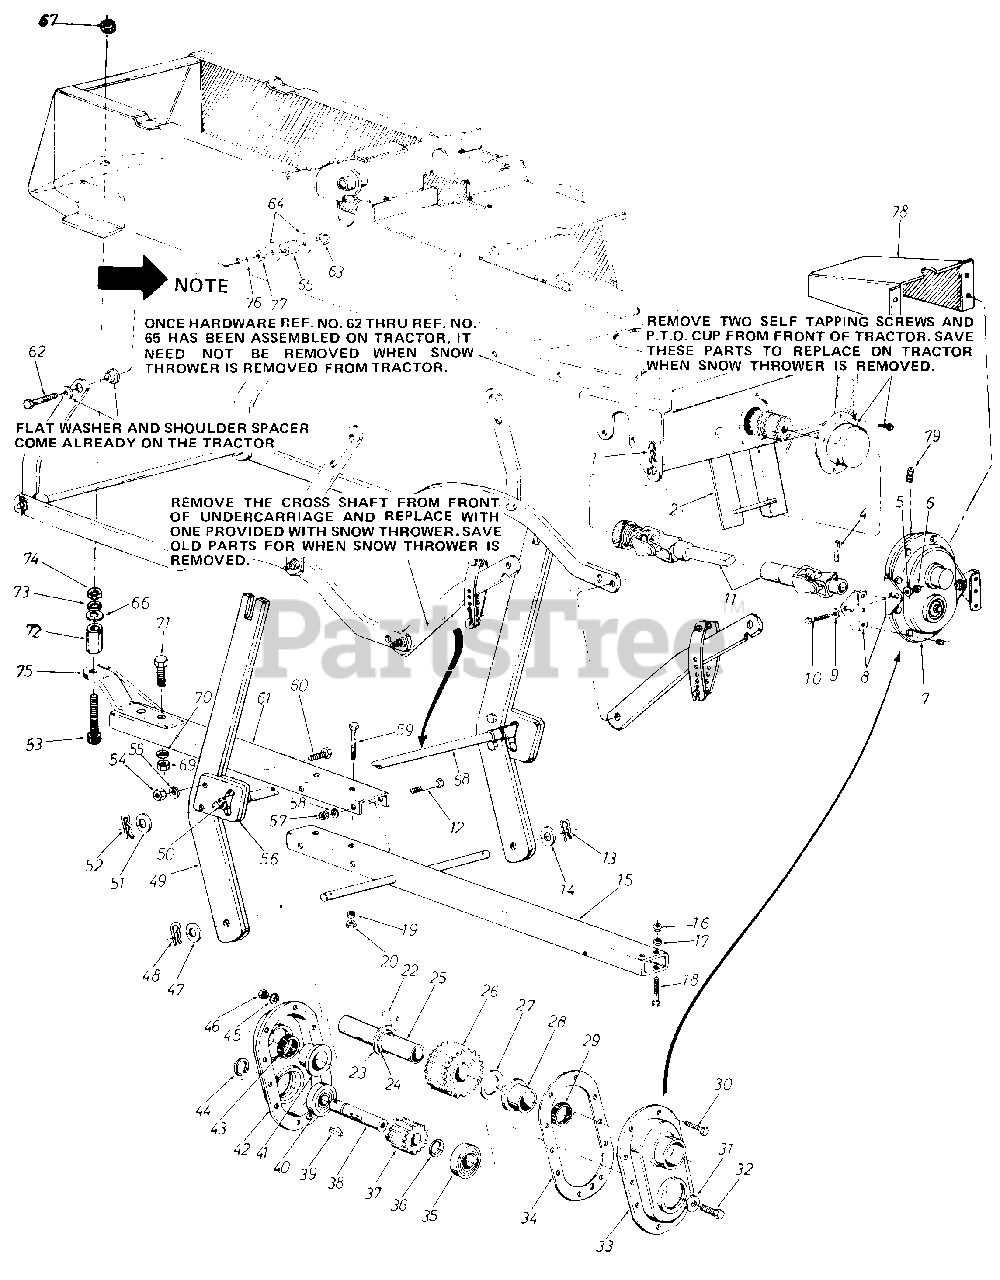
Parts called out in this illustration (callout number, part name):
1	Intern. Cotter Pin 3/4" Dia.
2	Guide Bracket Ass'y.
4	Spring Pin Spirol 1/4" Dia. x Lg.
5	Belleville Wash. .341" I.D. x.88" O.D.
6	Hex Nut 5/16-18 Thd.*
7	Gear Box Ass'y. Comp.
8	Gear Box Support Brkt.
9	Belleville Wash. .341 " I.D. x .88" O.D.
10	Hex Scr. 5/16-18 x 75" Lg.
11	Universal Drive Shaft Ass'y.
12	Hex Scr. 3/8-24 x 4.50" Lg.*
13	Hair Pin Cotter
14	Fl-Wash. .75" I.D. x 1.5" O.D.
15	Lift Shaft Ass'y.
16	Hex Ins. Jam L.-Nut 3/8-24 Thd.
17	L.-Wash. 3/8" Scr.*
18	Hex Scr. 3/8-24 x 2.75" Lg.*
19	L.-Wash. 3/8" Scr.*
20	Hex Ins. Jam L.-Nut 3/8-24 Thd.
22	Hi-Pro Key 1/4" x 7/8" Dia.
23	Fl.-Wash. 1.31" I.D. x 2.00" O.D. x .060
24	SnaP Rinq for 1.25" Dia. Shaft
25	Gear Shaft 1.25" Dia. x 6.0" Lg.
26	28 Teeth Spur Gear
27	F l.-Wash. 1.31 " I.D. x 2.00 O.D. x .060
28	Flange Bearing 1.25" I.D. x 1.75" O.D
29	Oil Seal 1.25" I.D. x 1.75" O.D. x .26
30	Hex Scr. 1/4-28 x .88" Lg.
31	Fl.-Wash. .40 I.D. x 1.25" O.D. x . 1 60
32	Hex L.-Scr. 3/8-24 x 1.00" Lg.
33	Complete Gear Housing Half- L.H.
34	Gasket
35	Ball Bearing 1.00" I.D. x 2.00" O.D.
36	Fl.-Wash. 1.03" I.D. x 1.63" x . 090
37	15 Teeth Spur Gear
38	Input Shaft
39	Woodruff Key 1/4" x 3/4" D ia.
40	Ball Bearing 1.00" I.D. x 2.00" O.D.
41	Flange Bearing 1.25" I.D. x 1.75" O.D.
42	Complete Gear Housing Half - . R . H .
43	Oil Seal 1.25" I.D. x 1.75 " O.D. x .26
44	Snap Ring for 1.00" Dia. Shaft
45	Spring Wash. 1/4" I.D.
46	Hex Nut 1/4-28 Thd.
47	Fl-Wash. .75" I.D. x 1.5" O.D>
48	Hair Pin Cotter
51	Fl.-Wash. .62" I.D. x 1.12" O.D.
52	Hair Pin Cotter
53	Hex Bolt 5/8-11 x 4.00" Lg.
54	Hex Nut 5/16-18 Thd.*
55	L.-Wash. 5/16" Scr.
58	L.-Wash. 3/8" Scr.*
59	Hex Scr. 3/8-24 x 2.75"
60	Hex Scr. 5/16-18 x 1.00" Lg.*
61	Lift Bracket
62	Hex Scr. 3/8-24 x 2.50"
63	Hex Jam L.-Nut 3/8-24 Thd.
64	Fl.-Wash...375 I.D. x 1.00" O.D x . 1 35"
65	Spacer .275 I.D. x .625 O.D. x .440
66	F l .-Wash . .62 " I . D . x 1.12 " O.D.
67	Hex Jam L-Nut 5/8-11 Thd.
68	Cross Shaft Ass'y.
69	Hex Nut 1/2-1 Thd.*
70	L.-Wash. 1/2" Scr.*
71	Hex Scr. 1 /2- 1 3 x 1 . 25 "
72	Bushing
73	L.-Wash. 5/8" Scr.*
74	Hex Jam Nut 5/8-11 Thd.
77	Hex Nut 3/8-2 Thd.*
78	Drive Shaft Cover
79	Grease Fitting
